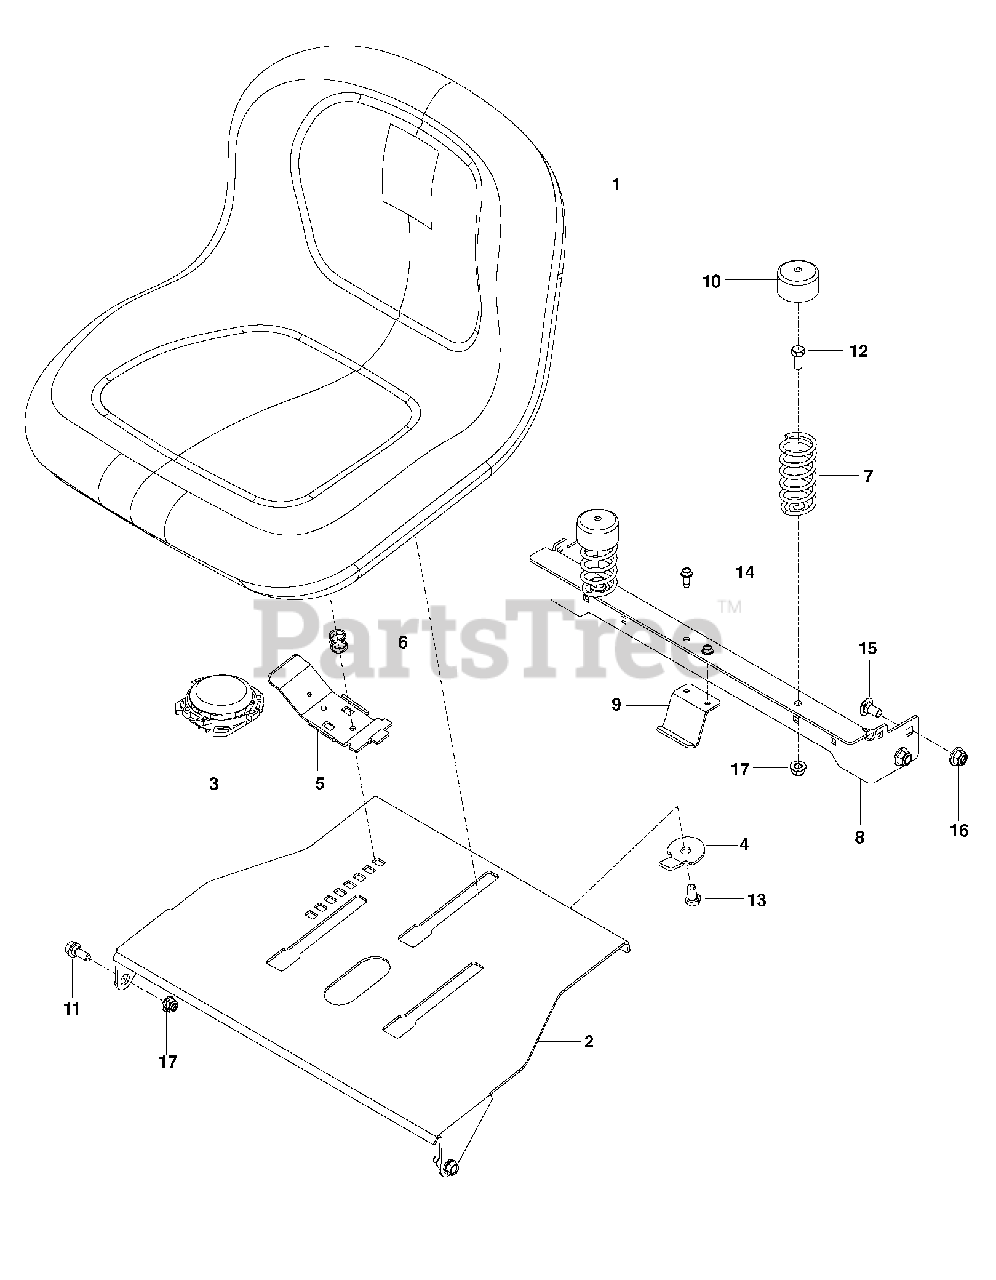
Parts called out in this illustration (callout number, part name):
1	SEAT,BLACK W/ARMREST PROVISION
2	PLATE, SEAT, ORG
3	SUPPORT, REAR SEAT, ORG
4	HOLDING DEVICE, FUEL TANK, BLK
5	SEAT SPRING
6	SPRING CAP
7	HANDLE.SLIDE.SEAT.TEX.BLACK
8	SWITCH, SEAT N/C
9	SPRING.LATCH.SEAT.TEX
10	STOP, SEAT, BLACK
11	BOLT, SHOULDER
12	HCS 5/16C X 3/4
13	HCS 3/8-16 X 5/8 GR 5 ZD
14	RHSNB 3/8-16 X 3/4 GR5 ZD
15	SCREW 1/4 X 5/8
16	5/16-18 NYLOC FLANGE NUT
17	NUT 3/8-16 HEX FLG NYLOC ZD
